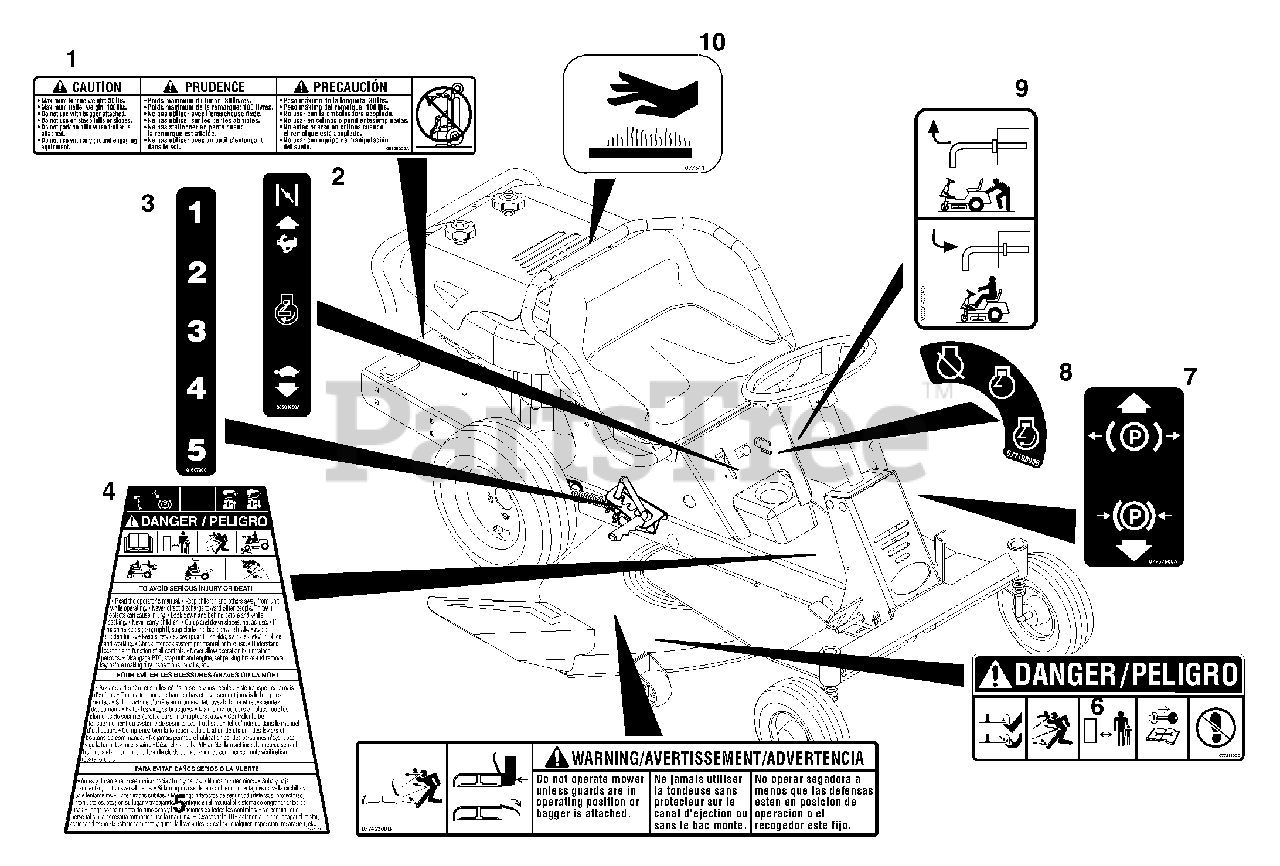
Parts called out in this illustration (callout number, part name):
1	DECAL-HITCH 100#
2	DECAL-THROTTLE RER/SPORT
3	DECAL, 5 POSITION CUT HEIGHT
4	DECAL-RER WARNING
5	DECAL, WARNING
6	DECAL, MOWER PAN DANGER
7	DECAL, PARKING BRAKE LEVER
8	DECAL - IGNITION
9	DECAL, TRANS DISCONNECT
10	DECAL, HOT SURFACE
